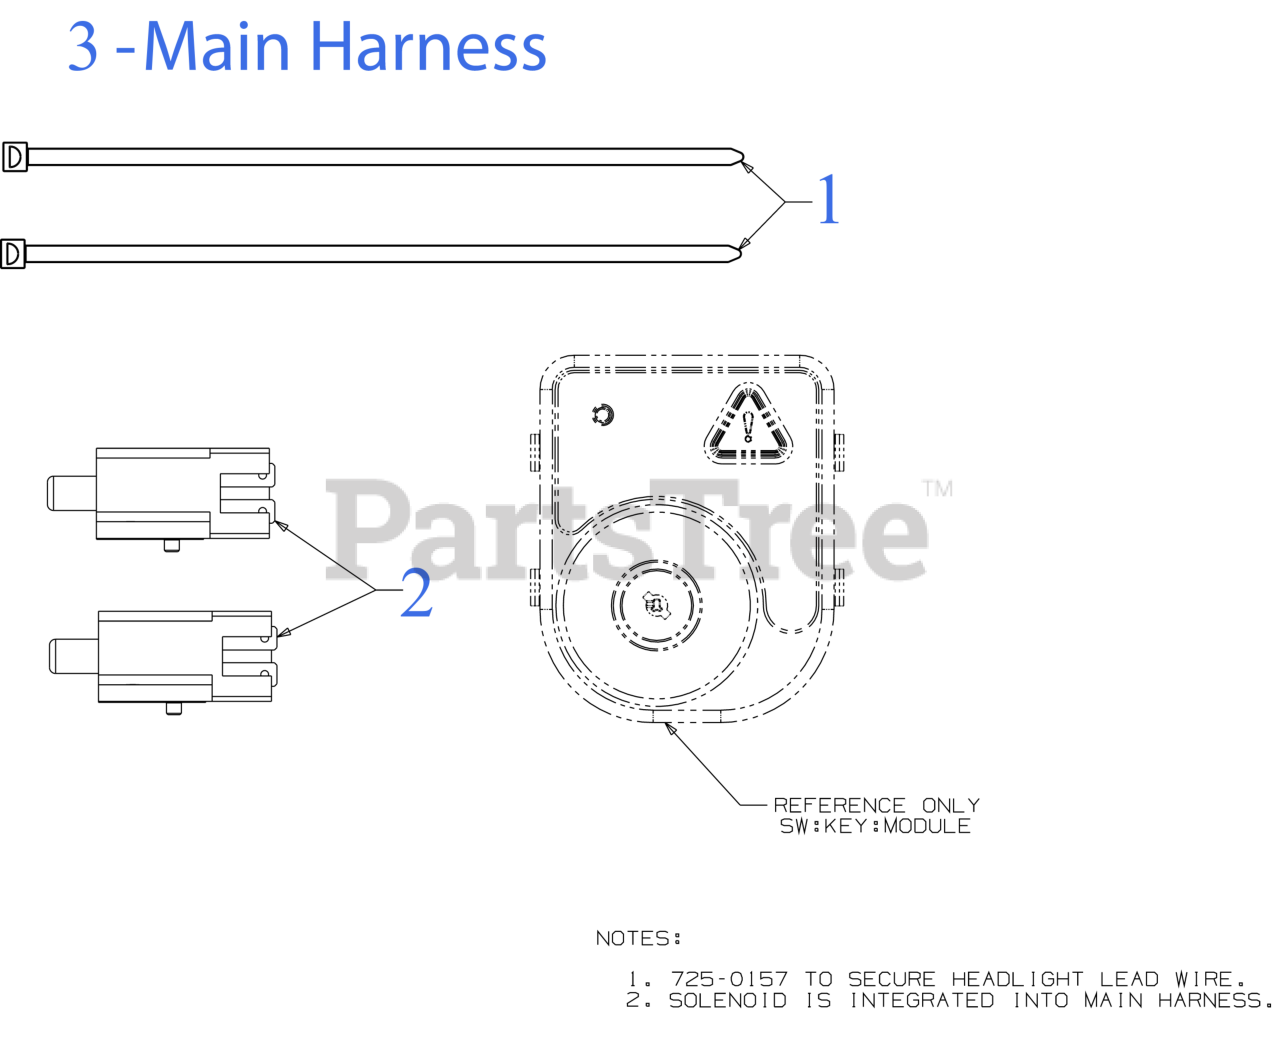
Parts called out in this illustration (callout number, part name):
1	7" CABLE TIE
2	INTERLOCK SWITCH (NO/NC)
3	MAIN HARNESS (RMC/MPTO/BULB/AGM)
3	12V SOLENOID
